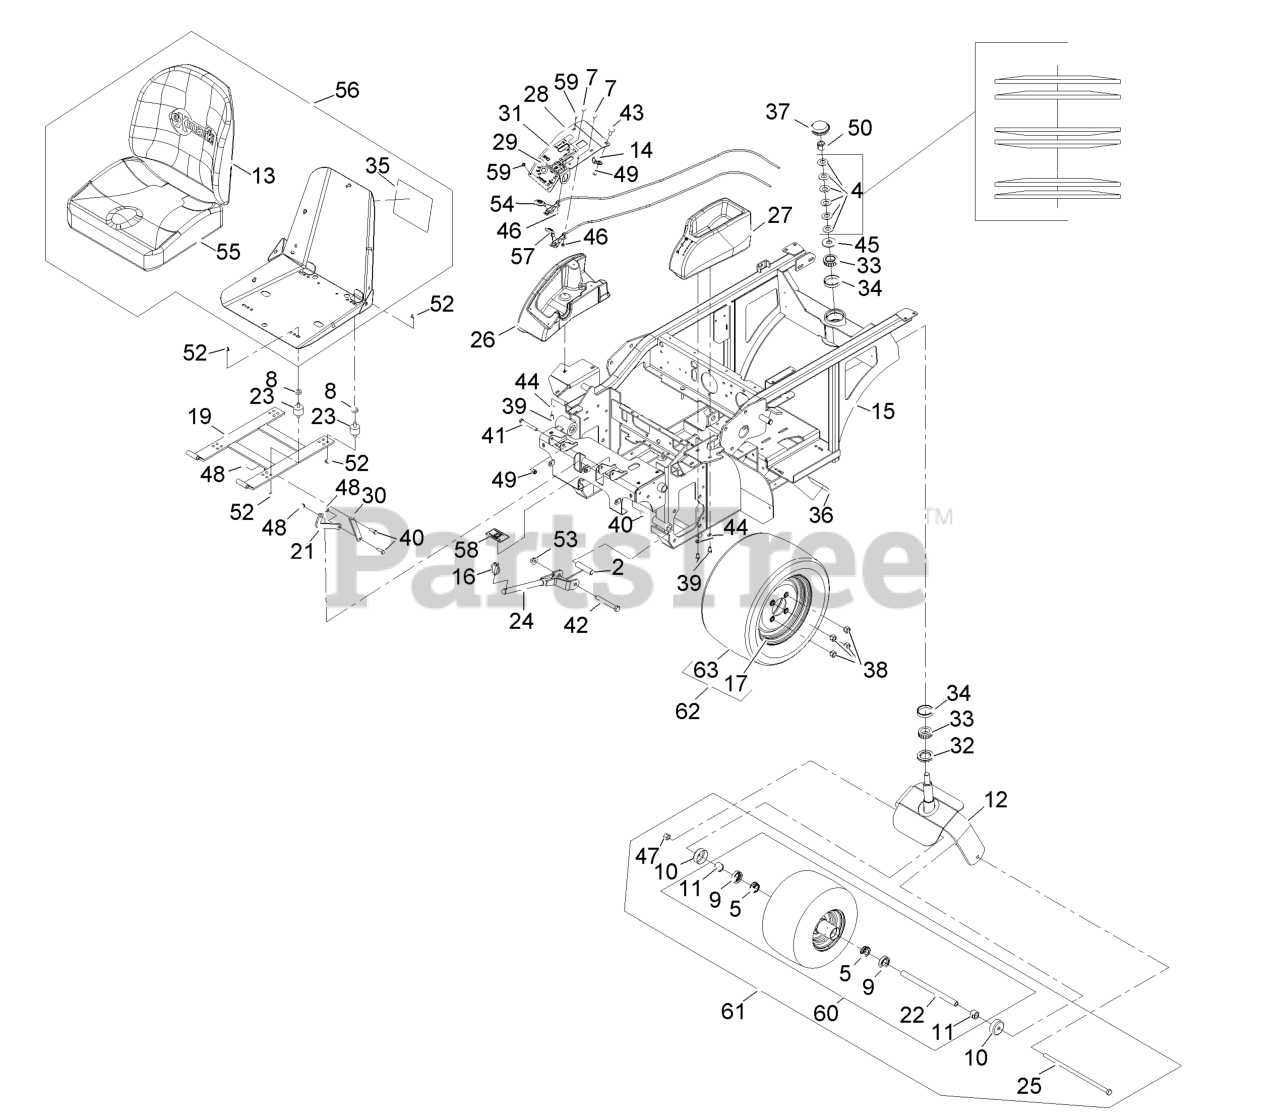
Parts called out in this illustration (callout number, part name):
2	SPACER-WHEEL, SHORT
4	WASHER-BELLVILLE
5	BEARING-CONE, TAPERED ROLLER
7	BOLT-CARR
8	SPACER
9	SEAL-CASTER
10	GUARD-SEAL
11	SPACER-NUT
12	FORK-REAR CASTER
13	CUSHION,SEAT BACK
14	CLIP-LOOM
15	ASM-FRAME W/DECALS AND BU
16	PIN-LYNCH
17	ASM,WHEEL
19	FRAME-SEAT
21	LINK-SEAT STOP, LOWER
23	MOUNT-VIBRATION, RUBBER
25	SCREW-HH
28	ASM-INTRUMENT PANEL W/DEC
29	DECAL,IGNITION/SPEED CONT
30	LINK-SEAT
31	DECAL,INSTRUMENT PANEL
32	SEAL-GREASE
33	BEARING-ROLLER, CONE TAPE
34	CUP-TAPERED, ROLLER BEARI
35	DECAL-SERVICE AID
36	DECAL,CLUTCH ADJUSTMENT
37	CAP-GREASE
38	NUT-LUG
39	SCREW-HH
40	SCREW-HH
41	SCREW-CARR
42	SCREW-HH
43	SCREW-CARR
44	WASHER-PLAIN
45	WASHER-FLAT
46	NUT-LOCK, NI
47	NUT-LOCK, NI
48	NUT-LOCK, NI
49	NUT-LOCK, NI
50	NUT-LOCK, NI
53	NUT-HHF
54	CABLE-CHOKE
55	ASM-SEAT BOTTOM CUSHION
57	CABLE-THROTTLE
58	DECAL,WHEEL MOTOR RELEASE
59	SCREW-PPH
60	ASM,WHEEL,TIRE & BRG SP
61	REAR CASTER WHEEL ASM
62	ASM,WHEEL & TIRE
